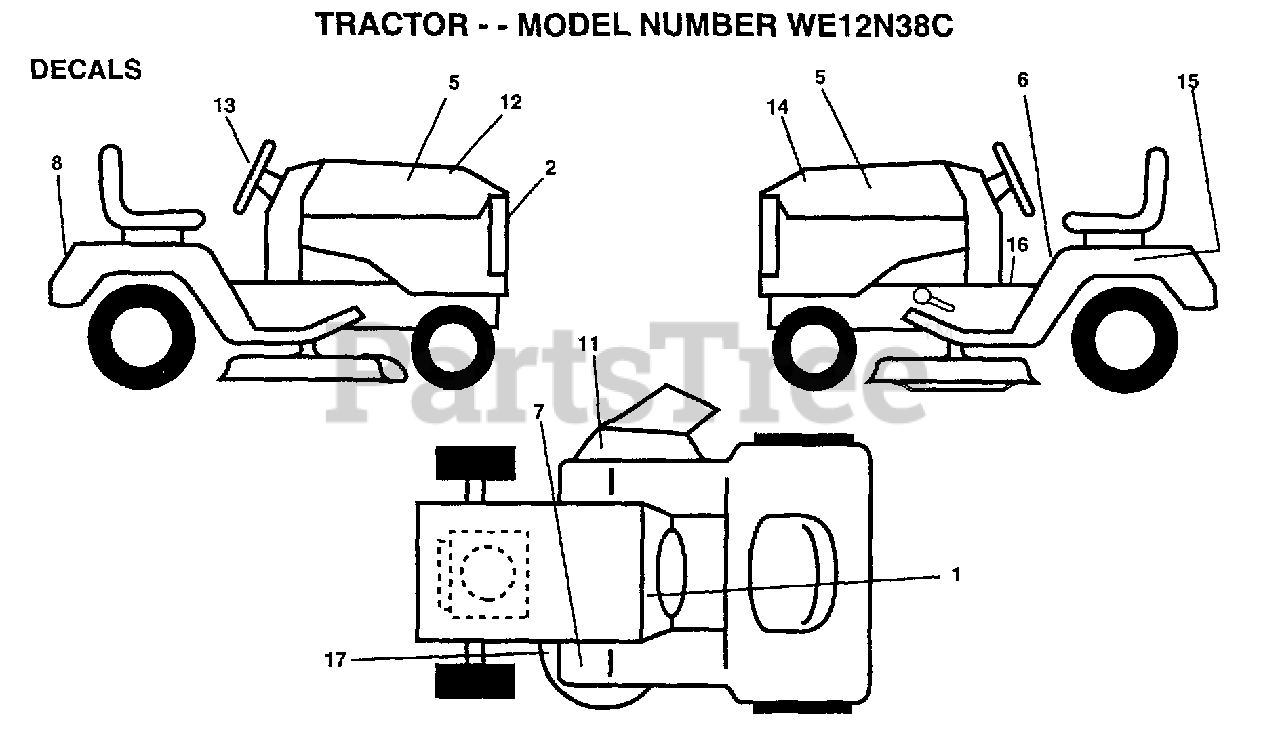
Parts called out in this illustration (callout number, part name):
1	DECAL.DASH.INSTR.
2	DECAL.GRILL
5	DECAL.PNL.SIDE.12
6	DECAL CAUTION
7	DECAL T
8	DECAL.FENDER
10	DECAL.MOWER
11	"DECAL, WARNING"
12	DECAL.HD.RH.WEED.
13	DECAL.WHL.STRG.
14	DECAL.HD.LH.WEED.
15	DECAL.BTRY.DANGER
16	DECAL BRAK PARK
17	DECAL
